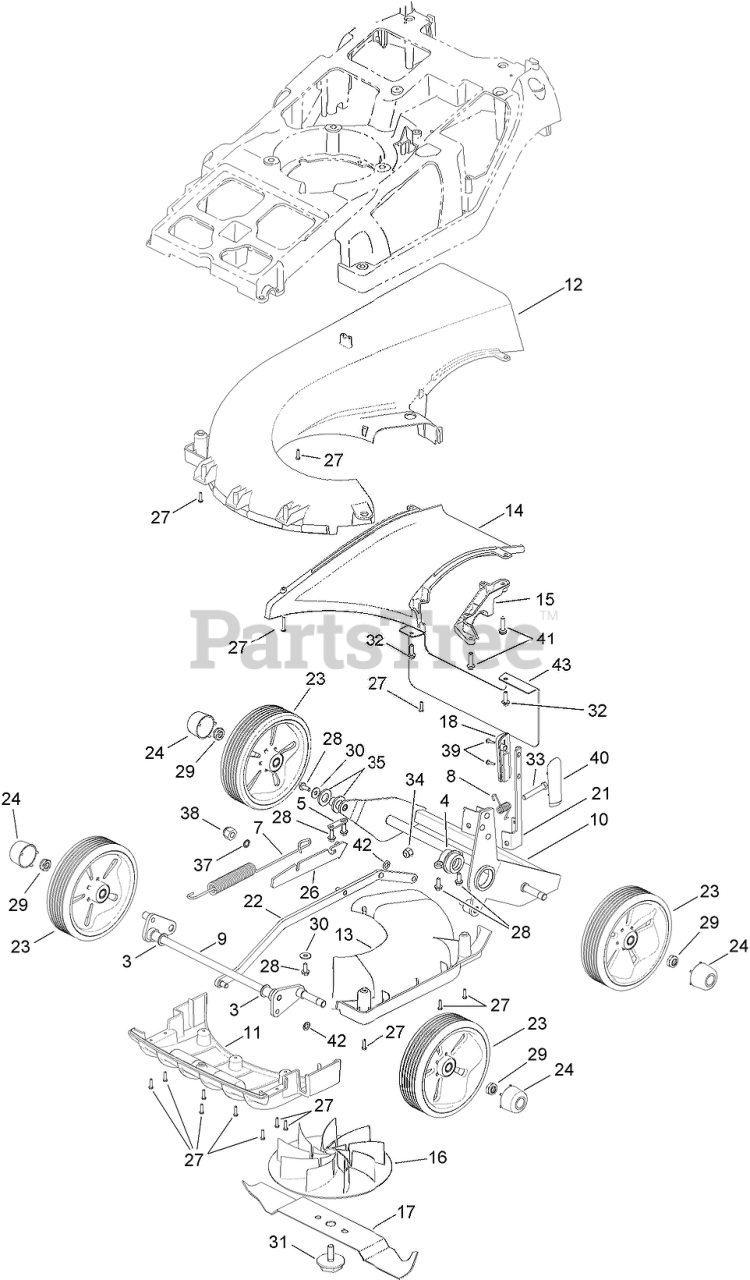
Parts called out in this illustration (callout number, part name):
3	BEARING-AXLE, FRONT
4	HOUSING-PIVOT BEARING, LH
5	PLATE-SECURING
7	SPRING-COUNTER BALANCE
8	SPRING-HOC
9	AXLE-FRONT
10	FRAME-WHEEL
11	MOULDING-FIN
12	MOULDING-SNAIL DECK
13	MOULDING-ACCESS, SNAIL DECK
14	MOULDING-THROW PLATE
15	MOUNT-BEARING
16	MOULDING-MOUNT, ELECTRIC BLADE
17	CUTTERBAR-ELECTRIC
18	KNOB-HOC, RH
21	LEVER-HOC
22	ROD-CONNECTING BAR
23	WHEEL ASM
24	CAP-WHEEL, CENTER
26	MOUNT-SPRING
28	SCREW M6 X 16 TAPTITE HEX HD
29	NUT-NYLOC
30	WASHER
31	BOLT-FIXING, BLADE
32	SCREW-TAPTITE
33	SCREW-HH
34	NUT-HEX, NI
35	WASHER-PLAIN
37	WASHER-SHAKEPROOF
38	NUT-NYLOC
40	KNOB-HOC, LH
41	SCREW-HH
42	WASHER-STARLOCK
43	GUARD-REAR
